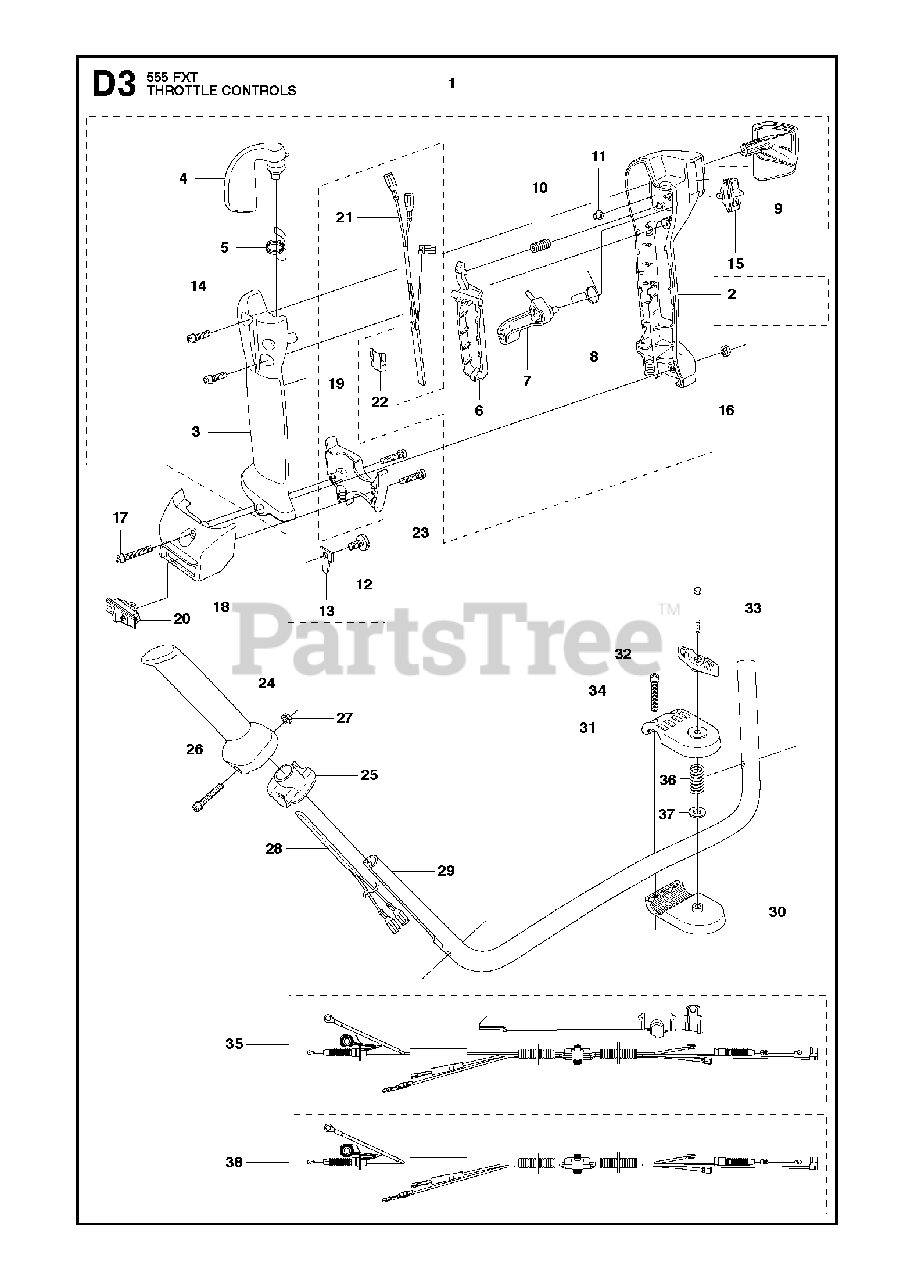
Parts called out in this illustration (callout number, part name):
1	THROTTLE HANDLE
2	HANDLE
3	HANDLE
4	THROTTLE TRIGGER
5	RP SPRING
6	THROTTLE LOCK
7	LEVER
8	SPRING
9	COVER
10	SPRING
11	SLEEVE
12	SCREW
13	HOLDER
14	SCREW
15	STOP BUTTON
16	NUT M6M M5
17	SCREW
18	HOLDER
19	HOLDER
20	SWITCH (G)
21	HEATING ELEMENT
22	HOLDER
23	SCREW
27	NUT M6M M5
28	HEATING ELEMENT
29	%HANDLE
30	HANDLE HOLDER LOWER
31	HANDLE HOLDER UPPER
35	WIRING ASSY KIT HUSQVARNA
38	WIRING ASSY
